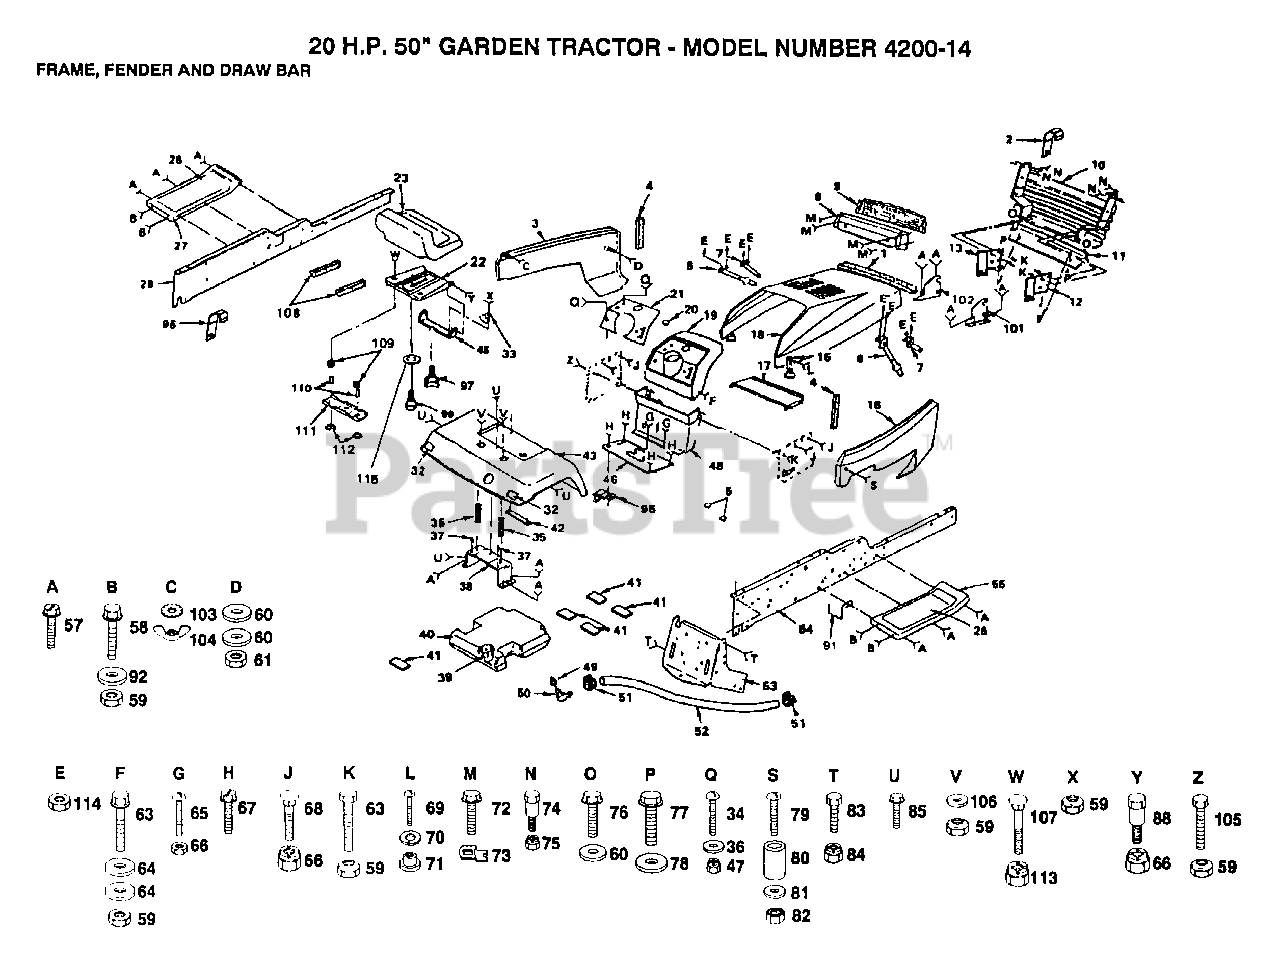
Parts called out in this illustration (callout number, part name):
1	FOAM STRIP T
4	FOAM STRIP T
5	CAP SPRING
9	LENS LT
12	SUPPORT RH YTH
13	SUPPORT LH YTH
15	HOOD LATCH T
20	PLUG-DASH T
23	SEAT
32	REFLECTOR-TAIL YT
33	CLIP T
34	SCREW
35	SPRING COMPRESSIO
36	WASHER
37	NUT-PUSH YT
41	PAD-SPACER LT
46	CVR GATE SHIFT
48	DASH ASSEMBLY
49	BUSHING OUTLET T
50	FUEL TANK STEM GT
51	HOSE CLAMP
57	SCREW
60	WASHER PM
63	BOLT
64	WASHER
65	SCREW
68	BOLT
69	SCREW
70	LOCKWASHER
71	WELDNUT
73	"""J"" FASTENER LT"
76	SCREW
77	SCREW
78	WASHER
79	SCREW
80	SPACER LT
81	WASHER
83	BOLT
84	NUT GTV
85	SCREW LT
91	BELT RETAINER GT
92	WASHER
97	"KNOB 1/2"" YT"
99	"BOLT,SHOULDER"
101	SUPPORT RH YTH
102	SUPPORT LH YTH
103	LOCKWASHER GT
106	WASHER
107	BOLT
108	STRIP FORM
109	SPRING COMPRESSED
110	SPACER SPLIT
111	BRKT SWITCH
112	BUSHING
114	NUT
115	WASHER
